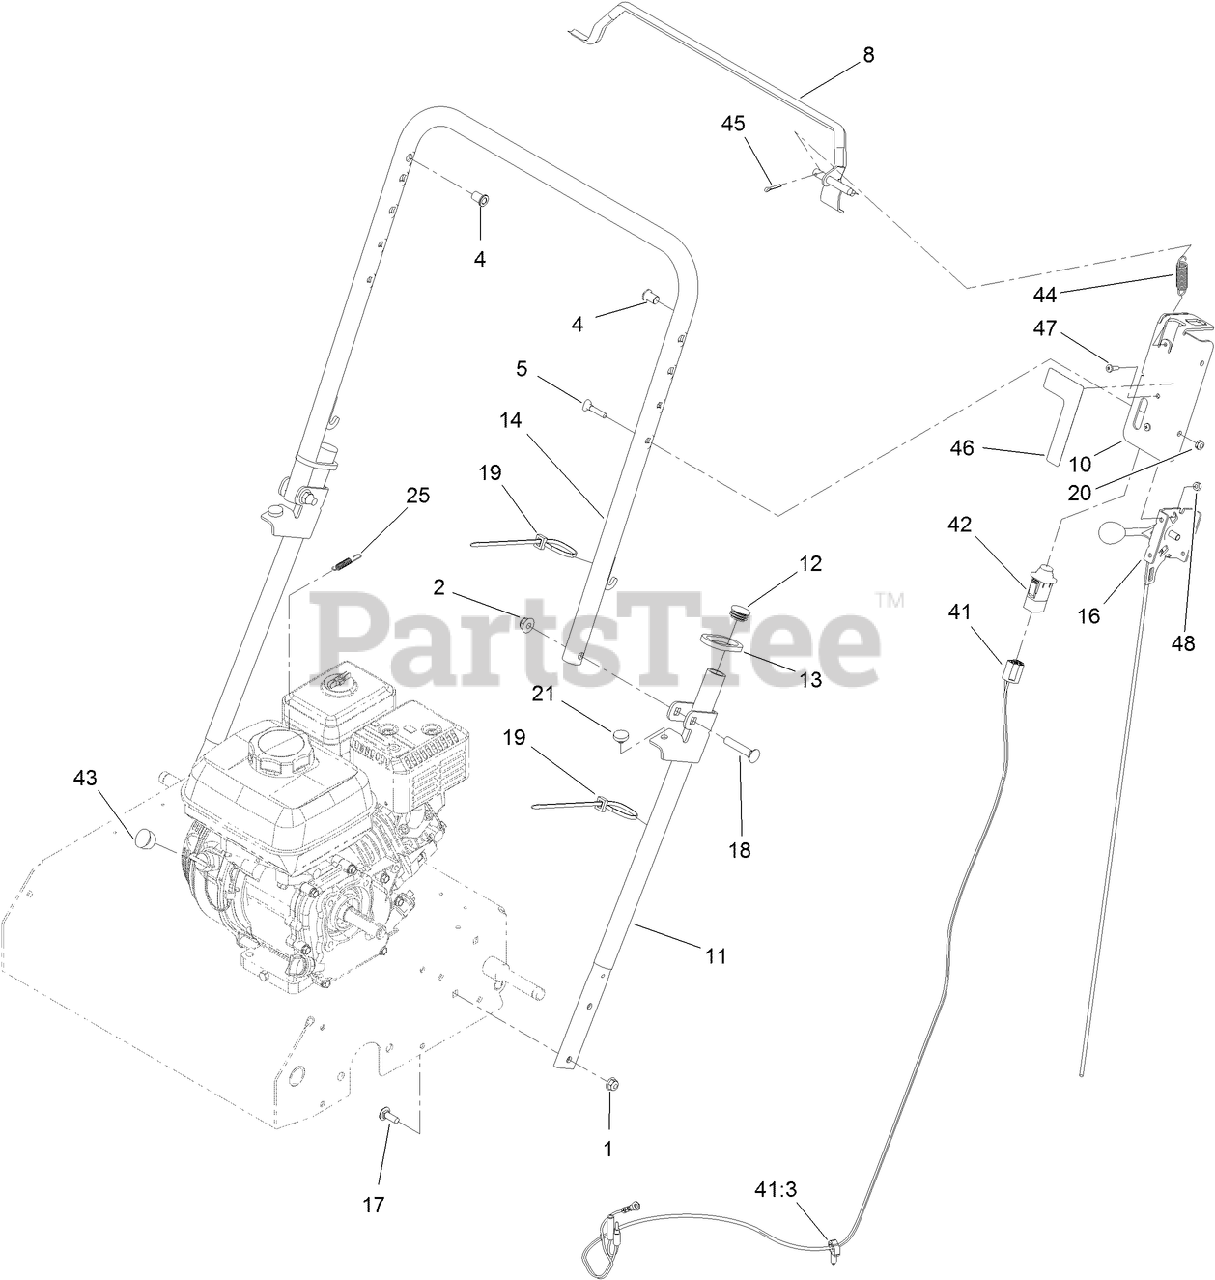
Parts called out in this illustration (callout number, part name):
1	NUT-HF, NI
2	NUT-HF, NI
4	BUSHING
5	BOLT-HANDLE
10	BRACKET-THROTTLE
13	RING-HANDLE LOCK
14	HANDLE-UPPER
16	CABLE-THROTTLE
17	BOLT-CARR
18	SCREW-CARR
19	TIE-CABLE
20	NUT-LOCK, NI
21	BUMPER
25	SPRING-EXTENSION
41	HARNESS-WIRE
41:3	CLIP-HARNESS
42	SWITCH-PLUNGER
43	PLUG-ENGINE
44	SPRING-EXTENSION
45	PIN-COTTER
46	DECAL-THROTTLE
47	SCREW-PPH
48	NUT-LOCK, NI
